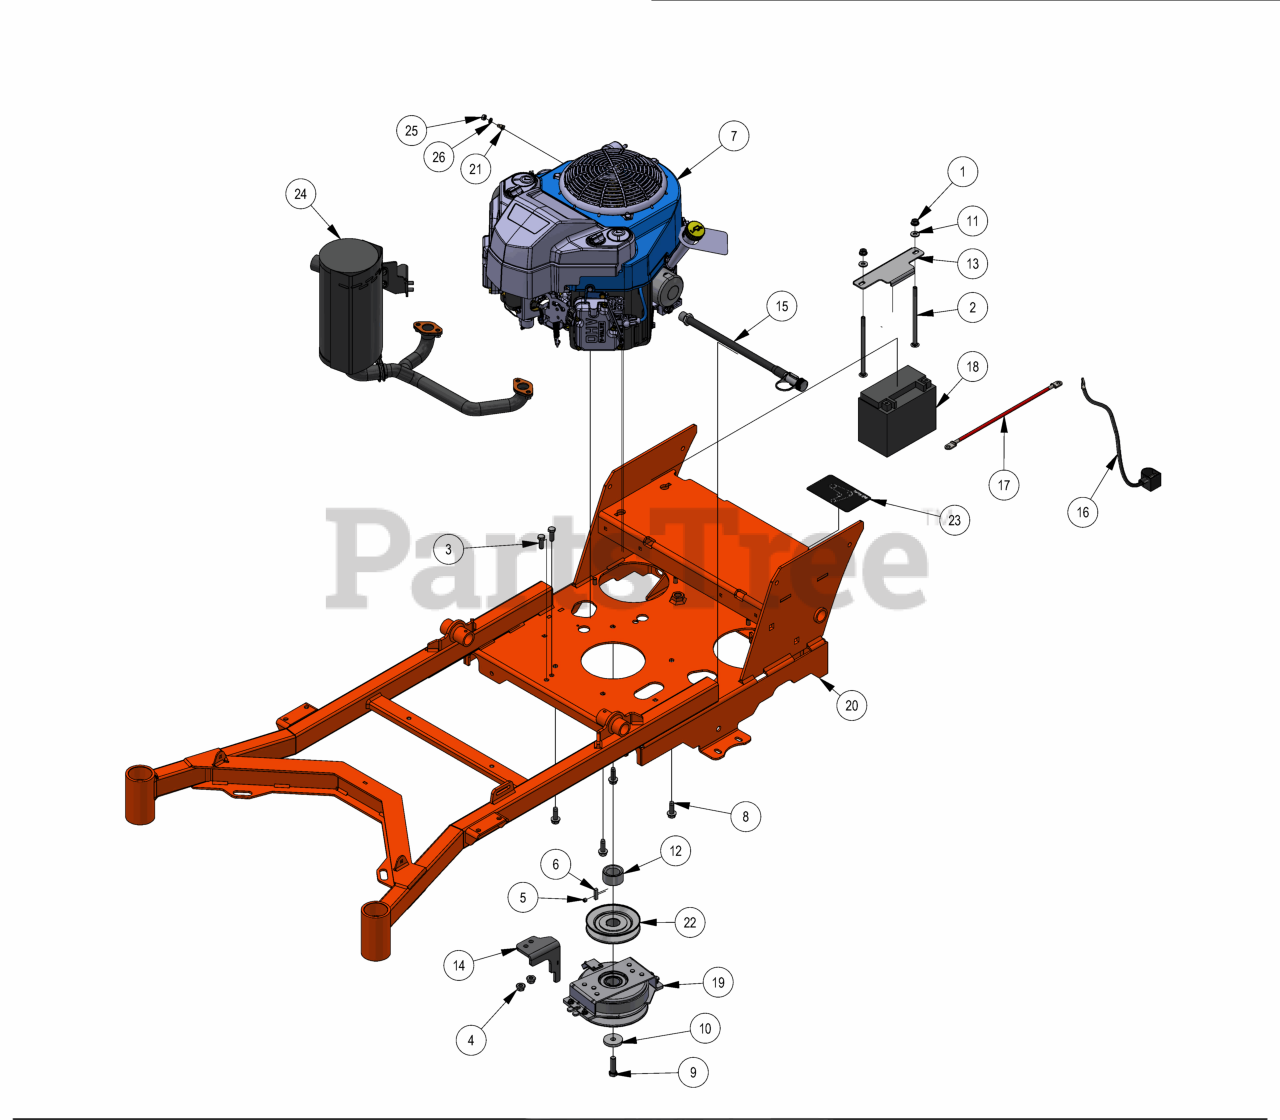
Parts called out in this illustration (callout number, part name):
1	5/16-18 NYLON INSERT FLANGE LOCKNUT ZINC
2	5/16-18 X 6 CARRIAGE BOLT (GR.5) ZINC
3	3/8-16 X 1 GR 5 Hex Bolts Zinc
4	3/8-16 NYLON INSERT FLANGE LOCKNUT (GR.F) ZINC
5	5/16-24 X 1/4 SOCKET SET SCREW (CUP PT) PLAIN
6	1/4 X 1 SQ MACHINERY KEY 1018 STL PLN
7	Kawasaki 18.5HP FS600 Electric Start
8	3/8-16 X 1-1/8 HEX WASHER UNSLOT SERRATED (TRI-LOB) TRS ZINC YELLOW
9	7/16-20 X 1-1/2 HEX CAP SCREW (GR.8) w/ Patch
10	CLUTCH WASHER
11	1/4 USS FLAT WASHER (3/4 OD) ZINC
12	1.130 x 1.75 x 1 Spacer, Countersunk, Zinc
13	Battery Hold Down Plate - Revolt
14	warner mgn clutch bracket v23
15	Kawasaki Oil Drain
16	24 inch Black Cable – MZ/ZT
17	12 in red battery cable
18	Interstate FAYTX14 Battery
20	2023 Walk Frame
21	Terminal 90 degree 6mm Spade
22	4 3/4" Motor Pulley
23	2017 Walk Behind 36" Deck Belt Route
24	Exhaust Assembly
25	1/4-20 Hex Nut
26	1/4 SPLIT LOCKWASHER ZINC
